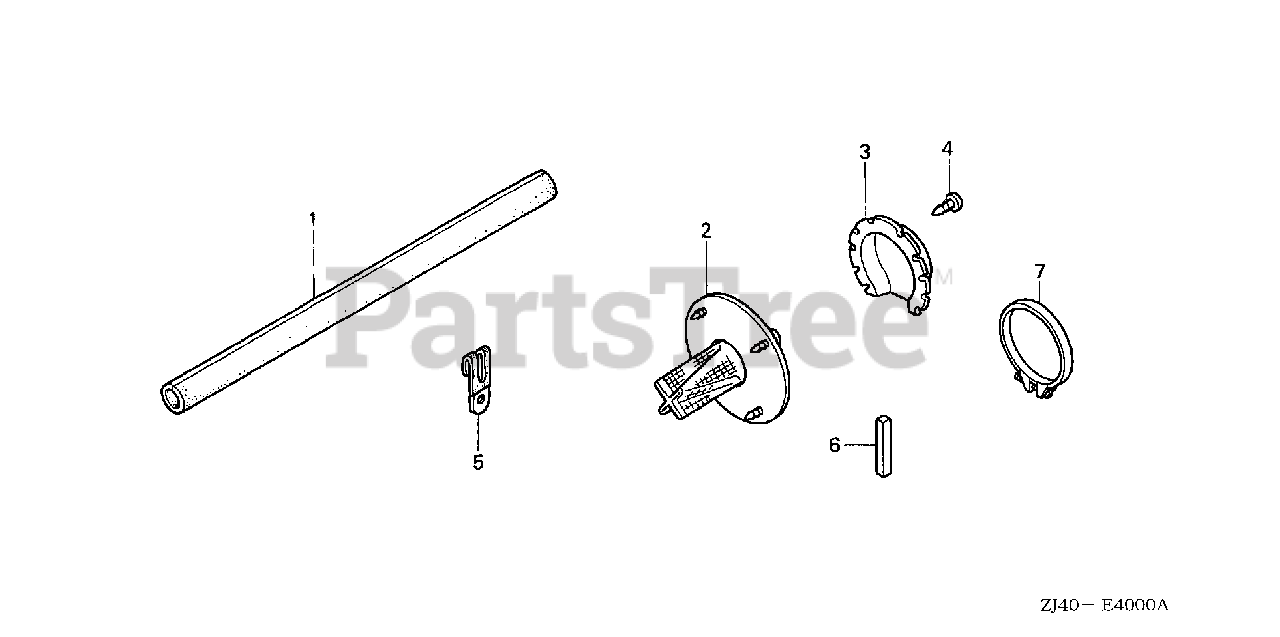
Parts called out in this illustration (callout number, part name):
1	RUBBER, SUPPORTER
2	ARRESTER, SPARK
3	DEFLECTOR KIT, EX.
4	SCREW (NELSON)
5	CLIP, WIRE
